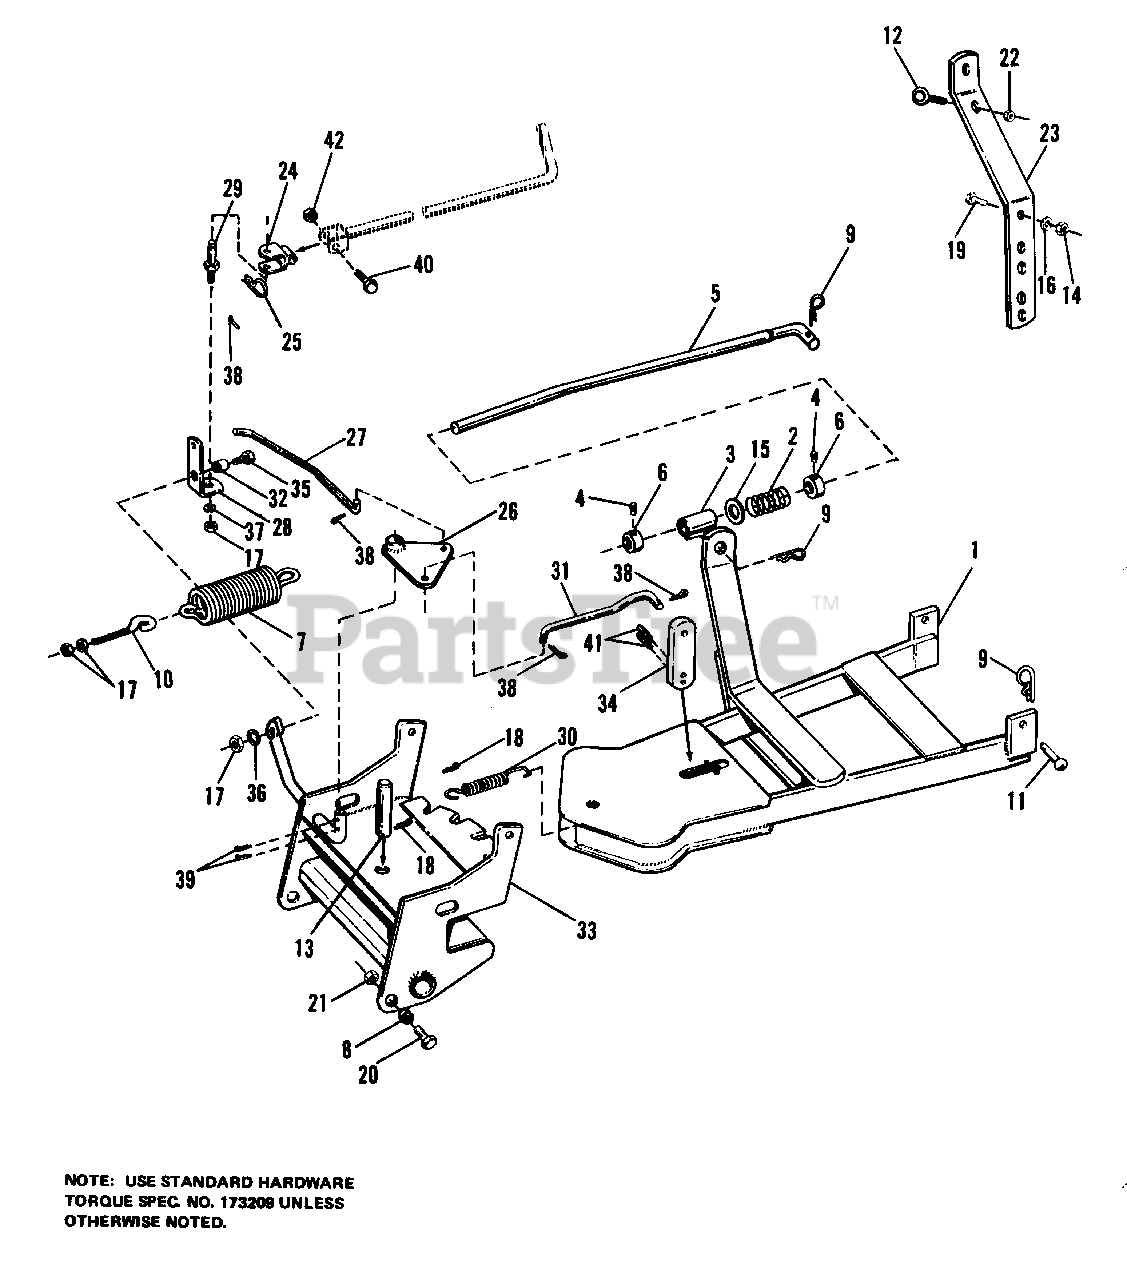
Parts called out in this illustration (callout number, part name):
1	BAR ASSY, Push
3	GUIDE ASSY, Rod
4	SETSCREW. Sq.Hd., 5/16-18 x 1/2
6	COLLAR
7	SPRING, Tension
9	CLIP, Spring
11	PIN, King
14	NUT, Hex, 3/8-16
15	WASHER, Plain, 1/2
16	LOCKWASHER, Spring, 3/8
17	NUT, Hex, 5/16-18
18	PIN, Cotter
19	CAPSCREW, Hex, 3/8-16 x 7/8
20	CAPSCREW, Hex, 1/2-13
21	NUT, Hex, Lock, 1/2-13
22	NUT, Hex, Lock, 1/4-20
23	BRACKET, Handle Support
25	CLIP, Spring
26	PLATE ASSY, Pivot
28	ARM, Pivot
29	STUD, Pivot
33	FRAME ASSY, Pivot
35	CAPSCREW, Hex Hd., 5/16-18 x 1
36	LOCKWASHER, Spring, 5/16
37	WASHER, Plain, 5/16
38	PIN, Cotter, 3/32 x 3/4
39	PIN, Cotter, 1/8 x 1
40	CAPSCREW, Hex Hd., 5/16-18 x 1-1/2
41	PIN, Spring, 7/32 x 1
42	NUT, Hex, 5/16-18
